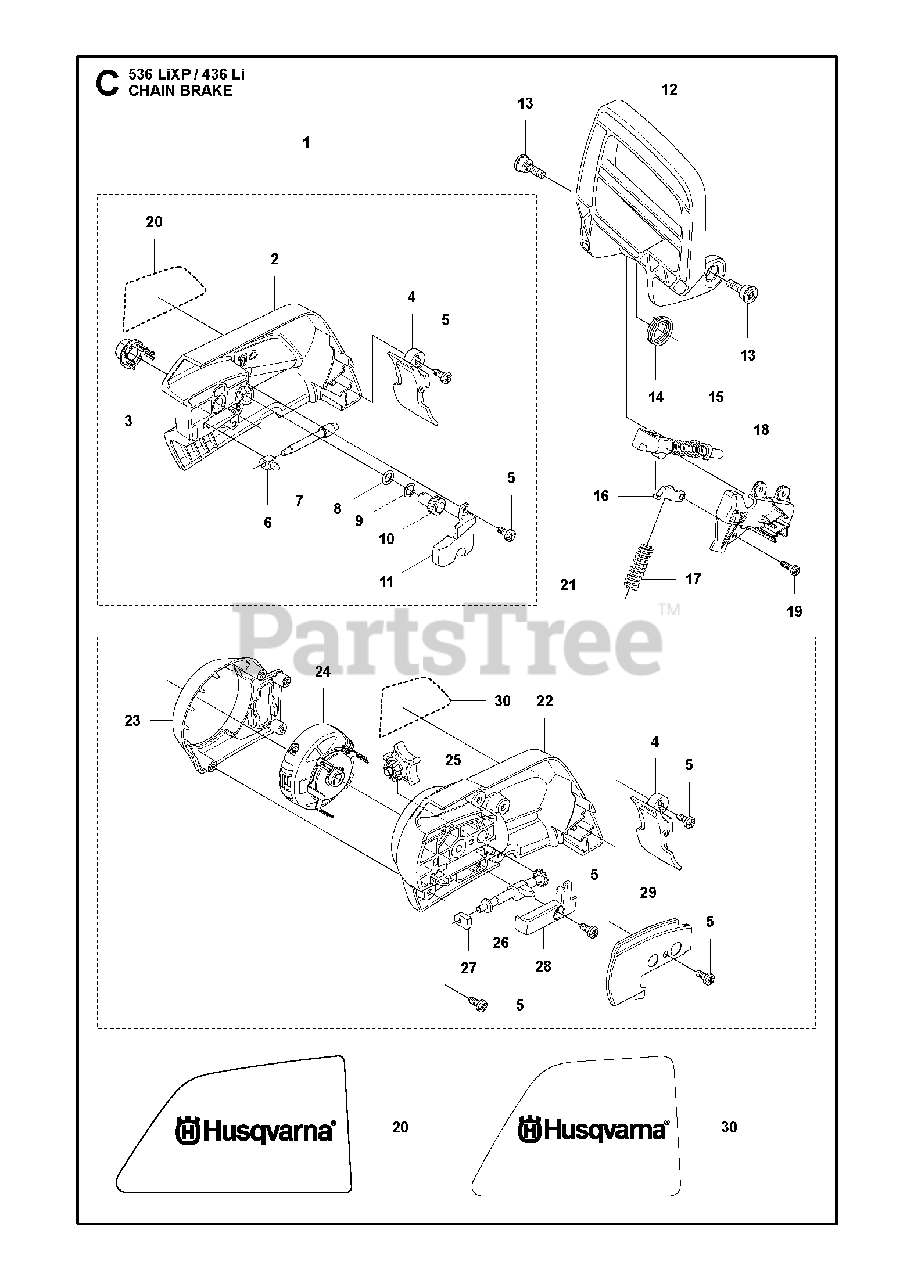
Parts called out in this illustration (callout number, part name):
1	CLUTCH COVER ASSY
2	CLUTCH COVER
3	NUT RETAINER ASSY
4	CHIP GUARD
5	SCREW
6	PAWL
7	SCREW
8	O-RING
9	WASHER
10	WORM WHEEL
11	COVER LID
12	HAND GUARD
14	TORSION SPRING
15	SHAFT ASSY
20	DECAL
21	CLUTCH COVER ASSY LI
22	CLUTCH COVER
23	COVER
24	KNOB UNLOSEABLE
25	CHAIN TENSIONER
26	CHAIN TENSION SCREW COMPL.
27	BEARING SLEEVE
28	COVER
29	WEAR PLATE
30	DECAL
